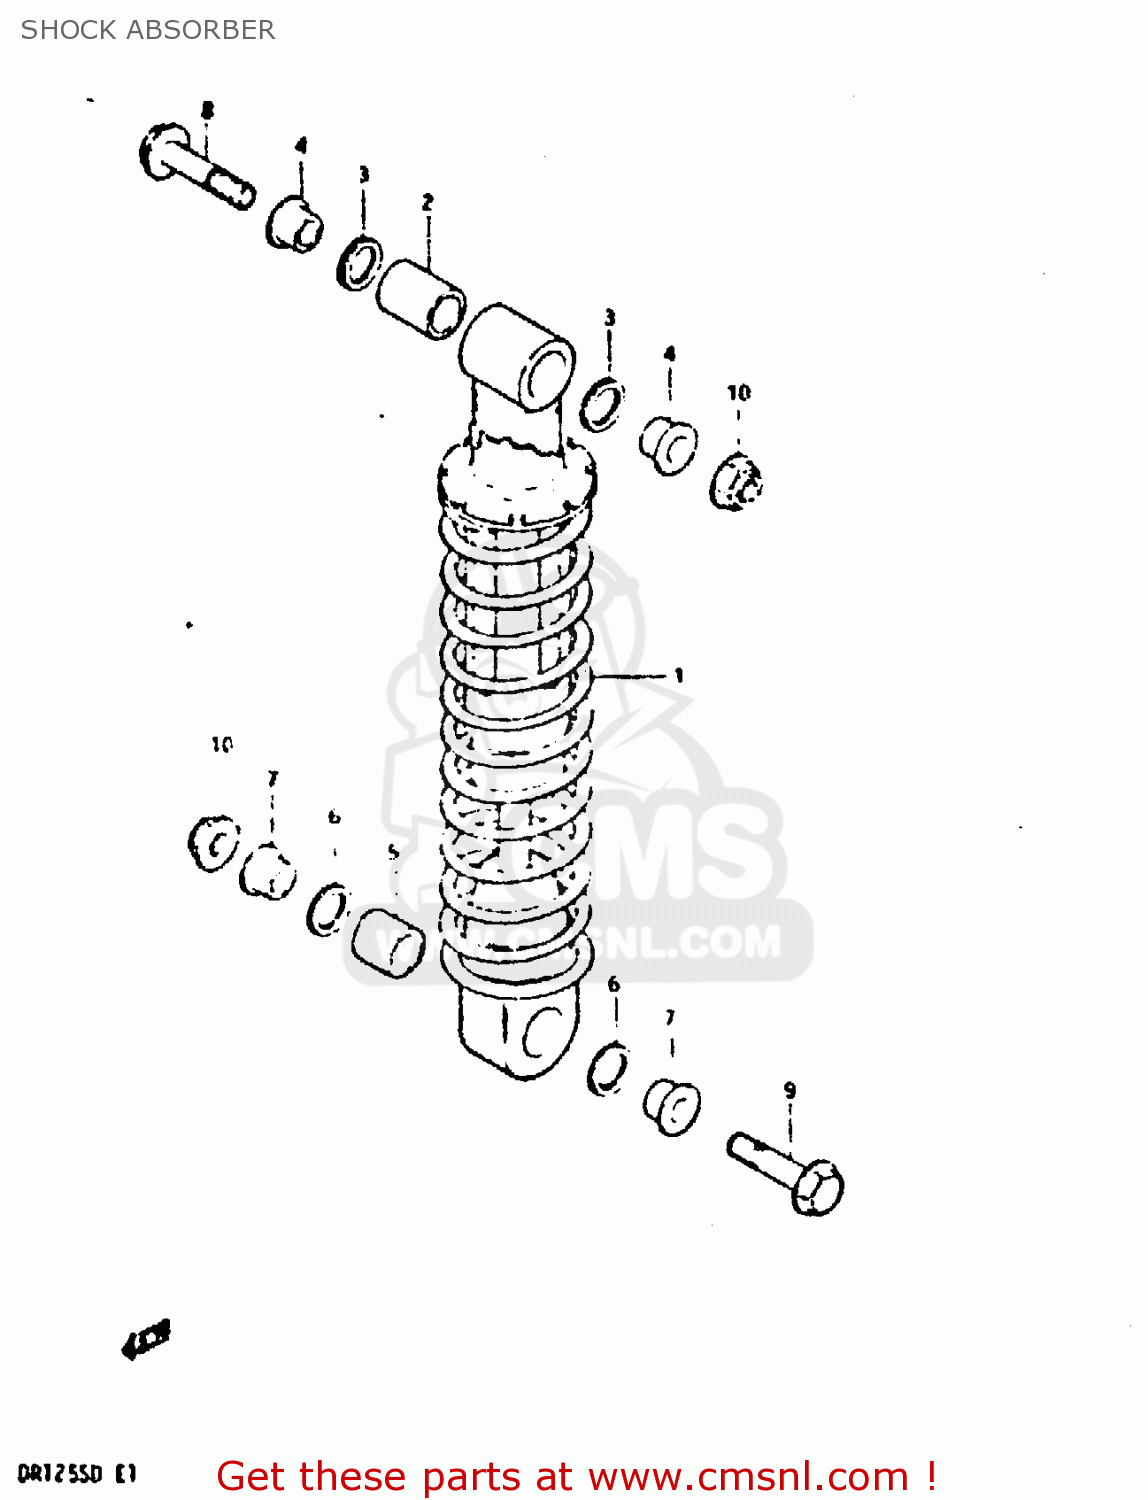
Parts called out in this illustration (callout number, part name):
1	ABSORBER ASSEMBLY,REAR SHOCK
2	BUSH,UPR
3	DUST SEAL,LEVER CUSHION UNIT
4	COLLAR,UPR
5	BUSH,LEVER CUSHION UNIT
6	DUST SEAL,LEVER CUSHION UNIT
7	SPACER,LEVER CUSHION UNIT
8	BOLT(10X60)
9	BOLT(10X50)
10	NUT
